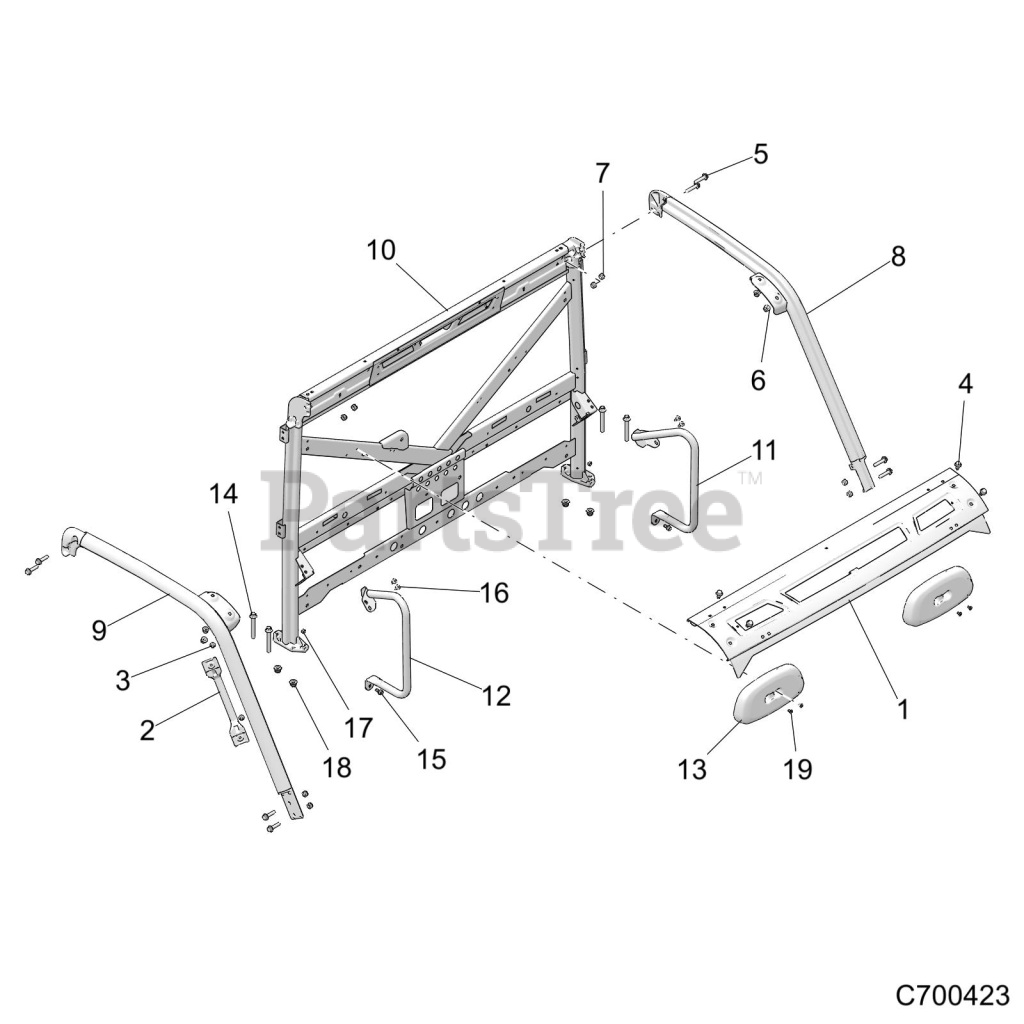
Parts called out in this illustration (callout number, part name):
1	PLATE-WNDSHLD MNT,UPR,BLK
2	HANDLE-GRAB,ROPS,BLK
3	BOLT-M8X1.25X20,HXFLG,TAP/R-OD
4	SCR-HXFL-M10X1.5X20 10.9 RIE P
5	SCR-HXFL-M10X1.5X45 10.9 RIE
6	NUT-HXFL-M10X1.5 8 ZB3 NYL
7	NUT-HEX-M10X1.5 10 ZB3 NYL
8	WELD-CAB FRAME,FRT,LH,M.BLK
9	WELD-CAB FRAME,FRT,RH,M.BLK
10	WELD-CAB FRAME,REAR,M.BLK
11	WELD-BOLSTER,LH, M.BLK
12	WELD-BOLSTER,RH,M.BLK
13	HEADREST-BLK
14	SCR-HXFL-M12X1.75X90 10.9 ZPC
15	SCR-HXFL-M8X1.25X20 8.8 ZOD P3
16	SCR-TXTH-M6X1.0X25 RIE
17	NUT-HEX-M8X1.25 10 P&O
18	NUT-HXFL M12X1.75 NYLOC ZOD
19	RIVET(50)
